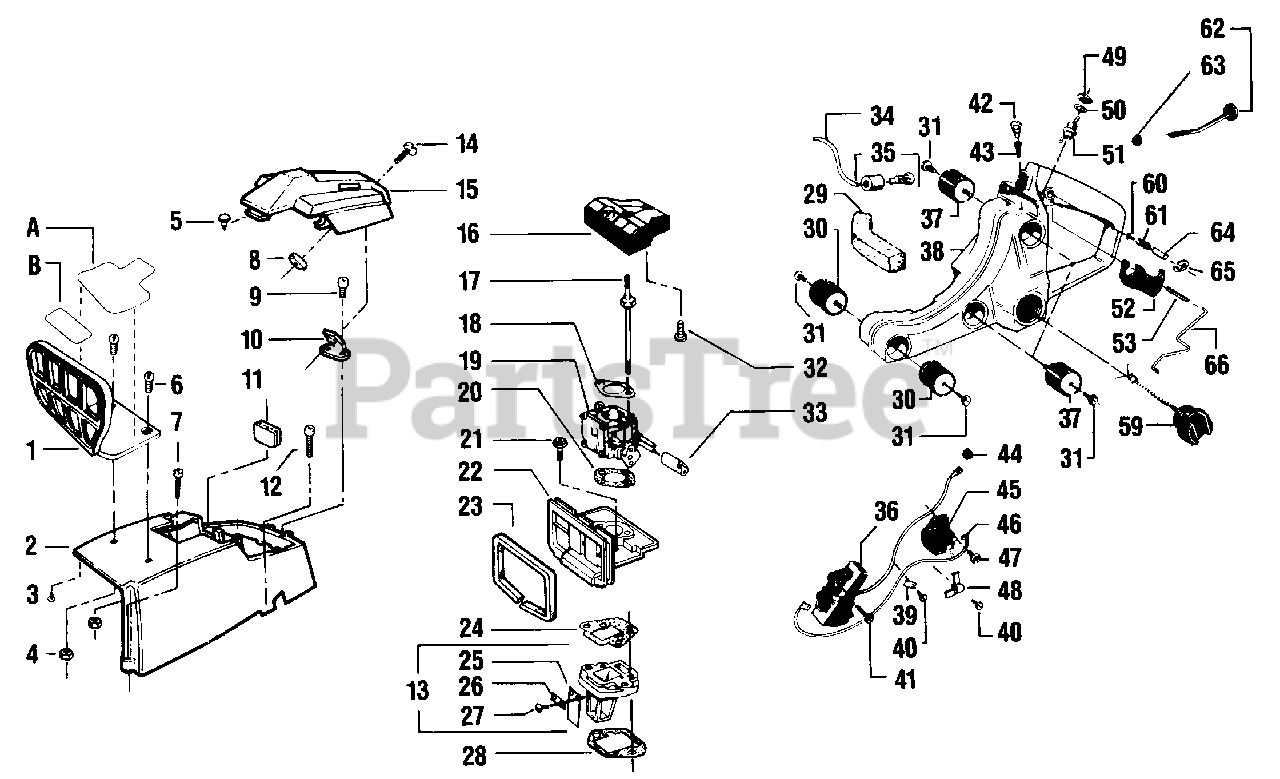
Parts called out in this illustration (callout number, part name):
1	Handguard
2	Cover - Cylinder
3	Drive Pin
4	Nut - 10 - 24
5	Bumper - Carb. - Cover
6	Screw - 10 - 24 x 1/2 Pan Hd.
7	Screw - Cylinder Cover #10 - 24 x 3/4
8	Retainer - Carb. Cover - Screw
9	Screw - Bracket Carb. Cover 10 - 16 x 1/2 HiLo
10	Bracket - Carb. Cover Retainer
11	Vent - Winter
12	Screw - Cyl. Cover #12 - 24 x 7/8
13	Reed Valve Assembly (Incl. #25, 26 & 27)
14	Screw - Carb. Cover 10 - 24 x 9/16 Fil. Hd.
15	Cover - Carburetor
16	Air Filter Assembly
17	Stud - Carburetor
18	Plate - Air Filter
19	Carburetor Assembly -
20	Gasket - Carb. to Adaptor Included in Engine - Gasket Kit 69180
21	Screw - Carb. Adapt. Reed Block - 10 - 24 x 1-1/4
22	Adaptor - Carburetor
23	Seal - Carb. to Adaptor
24	Gasket - Carb. Adaptor to Reed Valve Ass'y
26	Stop - Reed
27	Screw - Reed Mounting #4 - 40 x 1/8 Pan Head
28	Gasket - Reed Valve Assembly - C'Case Included in Engine - Gasket Kit 69180
29	Seal - Sawdust Included in Engine - Gasket Kit 69180
30	Mount Forward Isolator (Hourglass Shape)
31	Screw - Crankcase to Mounts - 10 - 24 x 1/2
32	Screw - Air Filter 10 - 16 x 1/2 - HiLo
33	Grommet - Carb. Adj. Screws
34	Line - Fuel Pick-up (Bulk No. 8136)
35	Fuel - Pick-up Assembly
36	Module - Ignition (Incl. #44 & 46)
37	Mount - Center and Rear Isolator (Cylindrical Shape)
38	Fuel Tank & Handle Ass'y. (Incl. #29, 60, 61, 64 & 65)
39	Clamp - Lead Wire Ignition
40	Screw - 8 - 32 x 5/16 - Tapping
41	Screw - Module Ignition - 10 - 24 x 7/8
42	Vent - Assembly - Fuel Tank (Incl. #42)
43	Check Valve - Fuel Tank Vent
44	Grommet - Lead Wire Included in Engine - Gasket Kit 69180
45	Transformer Ass'y. (Incl. #59 p. 1)
46	Lead Wire - Module/Transformer
47	Screw - 10 - 24 x 3/4 Hex Washer Hd. - Transformer
48	Clamp - Lead Wire
49	Nut - Switch Mounting
50	Lockwasher - Switch Mtg.
51	Switch - Ignition
52	Trigger - Throttle
53	Pin - Trigger
59	Fuel Cap Ass'y. (Incl. O-Ring)
60	Spring - Throttle Lock
61	Pin - Throttle Lock
62	Choke Knob
63	Grommet - Choke Rod Included in Engine - Gasket Kit 69180
64	Sleeve - Throttle Lock
65	"E" Ring - Throttle Lock
66	Wire - Throttle
A	Decal - Starting Instructions
B	Decal - Kickback
